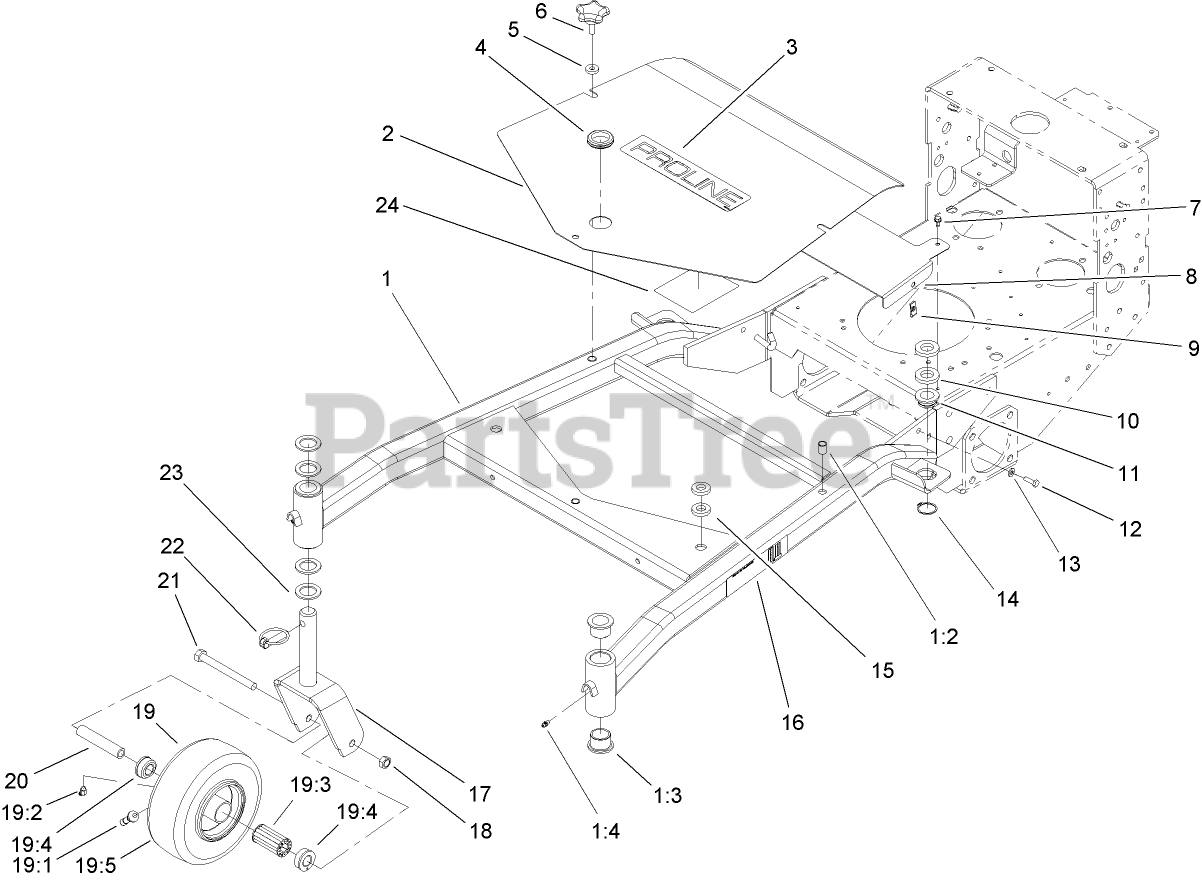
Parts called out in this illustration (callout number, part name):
1	Carrier Frame ASM
1:2	INSERT-NUT
1:3	BUSHING
1:4	FITTING-GREASE
4	GROMMET-RUBBER
5	WASHER-RUBBER
7	SCREW
8	Shield-Heat
9	NUT-SPEED
10	SPACER-SUPPORT, DECK
11	BUSHING-DECK
12	SCREW-HH
13	WASHER-FLAT
14	RING-RETAINING
15	SPACER
16	DECAL-HOC
17	FORK-CASTOR
18	NUT-HEX
19	CASTER WHEEL ASM
19:1	STEM-VALVE
19:2	FITTING-LUBE, 45 DEG
19:3	BEARING
19:4	BEARING-OUTSIDE
19:5	TIRE-TUBELESS
20	BUSHING-SPANNER
21	SCREW-HH
22	PIN-LYNCH
23	WASHER-THRUST
24	DECAL-SERVICE, HYDRO (TBAR)
24	DECAL-SERVICE, GEAR (TBAR)
24	DECAL-SERVICE, GEAR (PISTOL GRIP)
24	DECAL-SERVICE, HYDRO (PISTOL GRIP)
